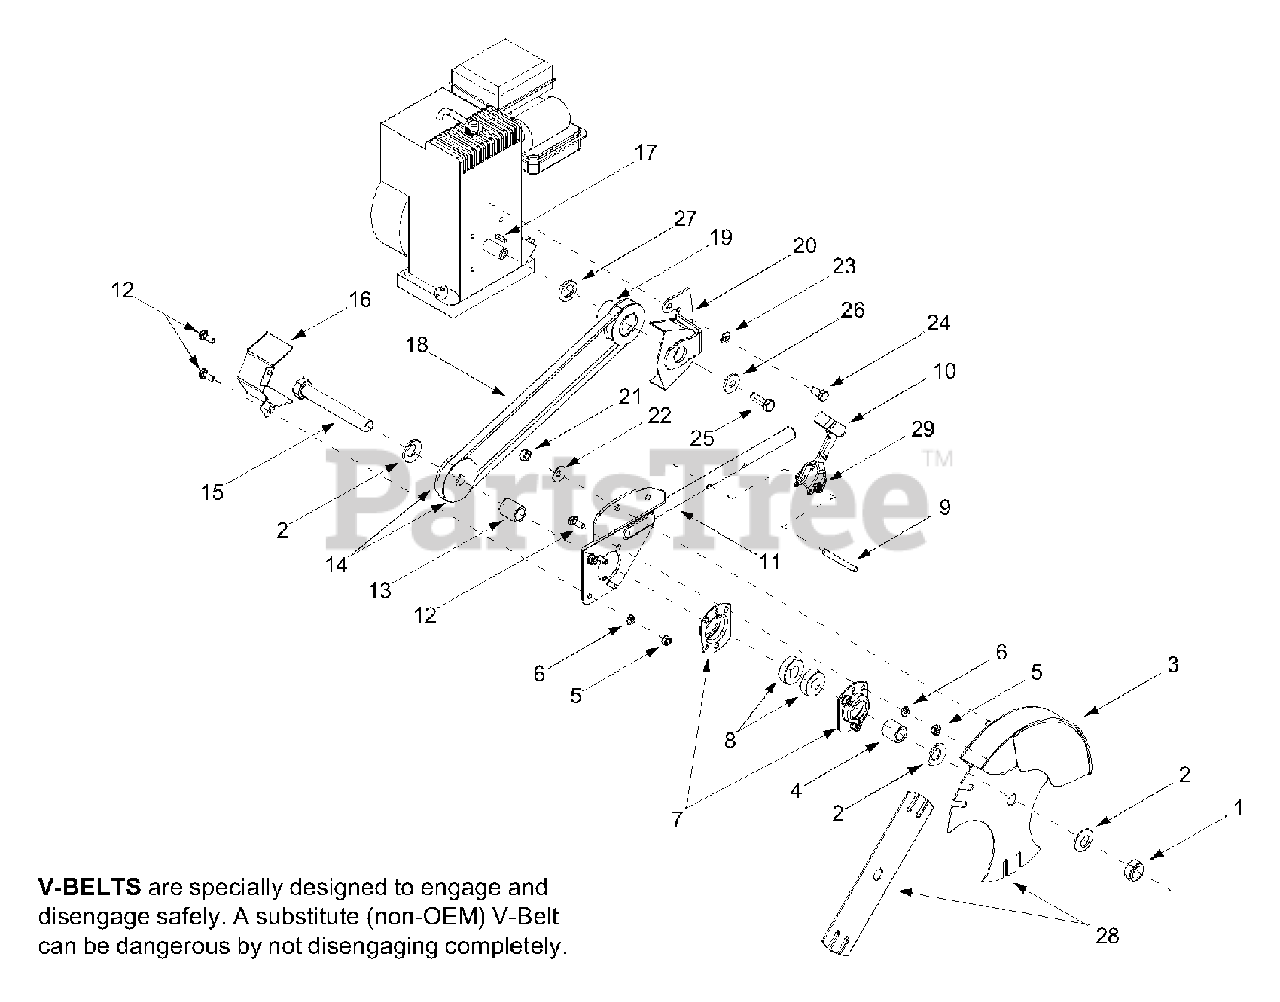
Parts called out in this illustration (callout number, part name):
1	Hex Jam Nut, 5/8-18
2	Bell Washer, .64 x 1.25 x .18
5	Hex Nut, 1/4-20
6	Lock Washer, 1/4
7	Bearing Housing
8	Ball Bearing, .62 x 1.38 x .44
9	Spirol Pin, 1/4 x 2.0
10	Adjustment Lever Assembly
13	Spacer, .635 x .88 x 1.03
14	Sheave, .6255 x .6295
15	Hex Cap Screw, 5/8-18 x 4.5
17	Square Key, 3/16 x .75
18	V-belt, 3/8
19	Engine Pulley, 3/8 x .75 x 2.38
22	Belleville Washer, .340 x .872
23	Lock Washer, 5/16
24	Hex Cap Screw, 5/16-24 x .625
25	Hex Cap Screw, 3/8-24 x 1.0
26	Flat Washer, .385 x 1.0 x .135
27	Spacer, .753 x 1.25 x .175
29	Double-torsion Spring
